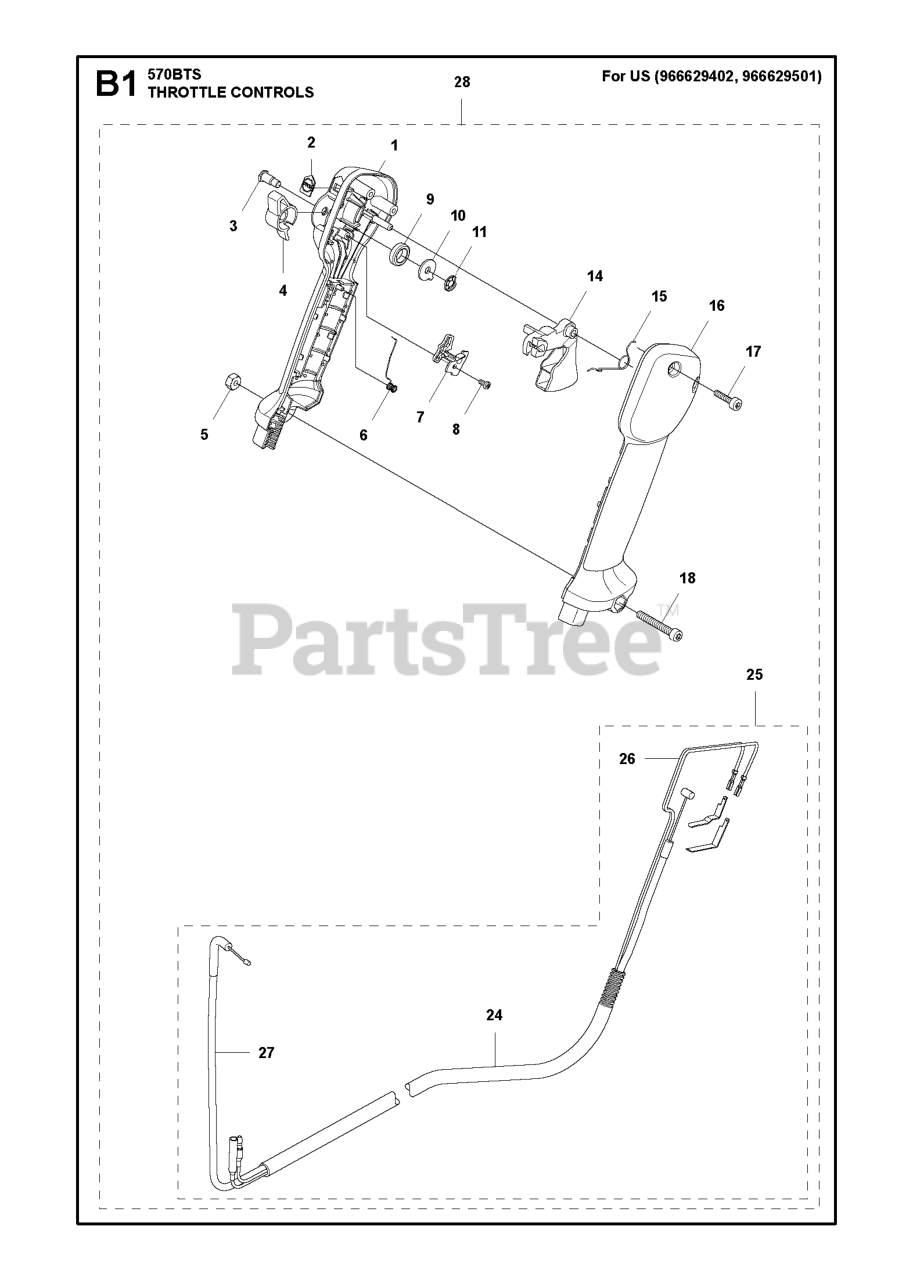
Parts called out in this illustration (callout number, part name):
1	HANDLE HALF (L)
3	SHAFT PIVOT
4	LEVER STOP
14	TRIGGER 848L5W34C0
16	HANDLE HALF (R)
17	SCREW
25	WIRING ASSY
26	CORD COMPLETE
27	CABLE, COMP
28	ASSY LEVER SET
